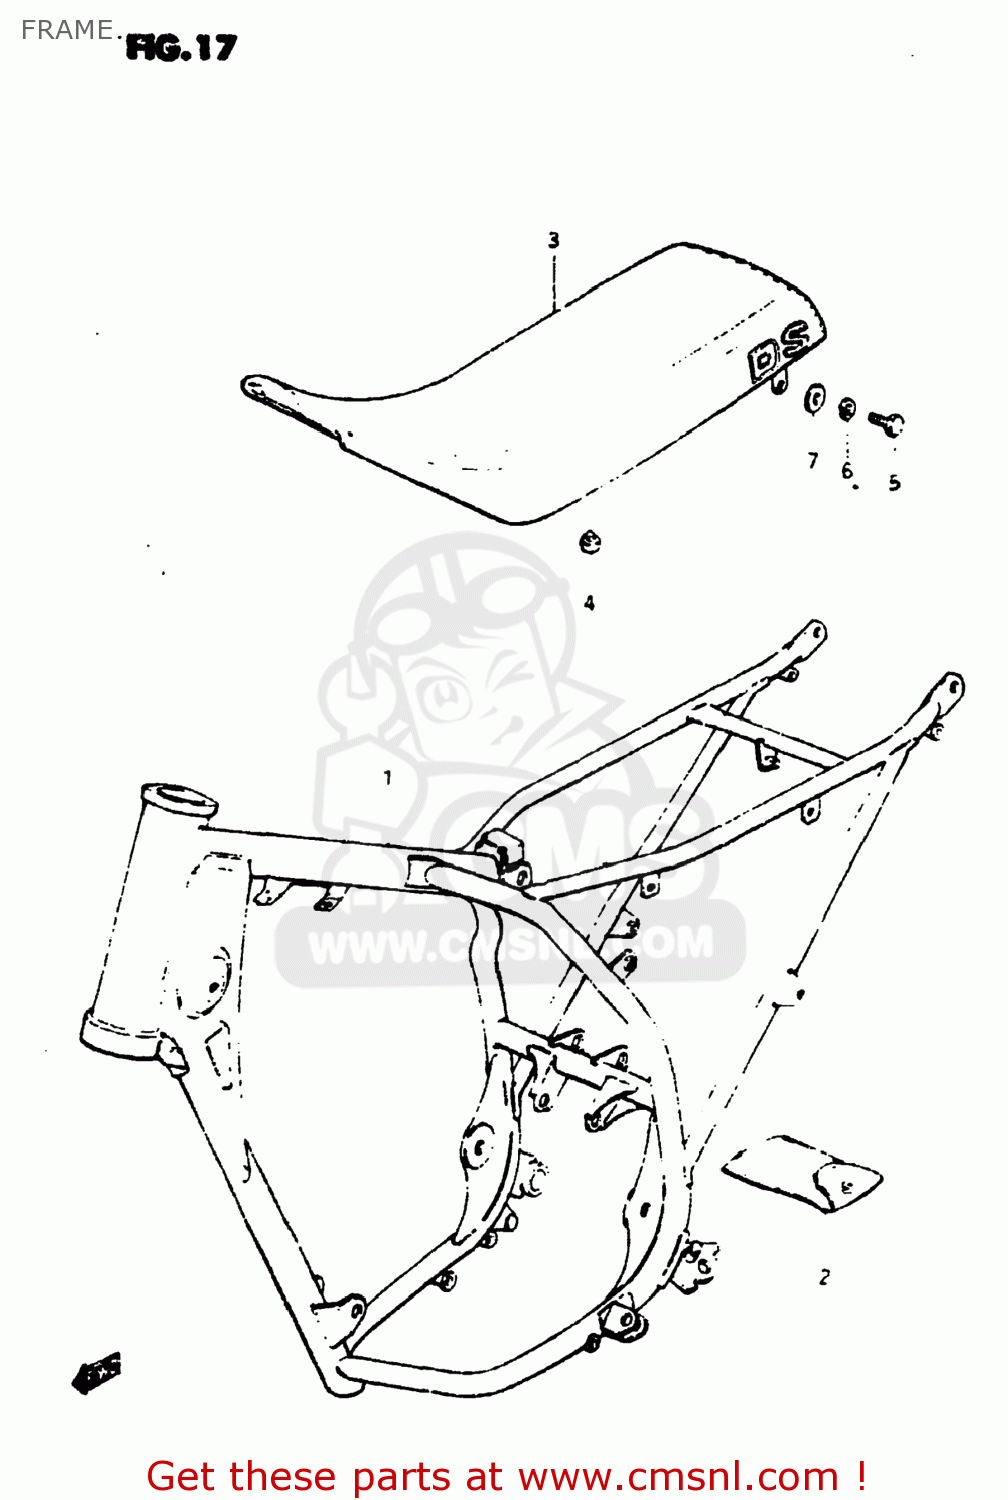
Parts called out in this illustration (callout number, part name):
1	FRAME(BLACK)
2	TOOL ASSY
3	SEAT ASSEMBLY
4	CUSHION
5	BOLT, UPPER
6	LOCK WASHER
7	WASHER (6.5X18X1.6)
